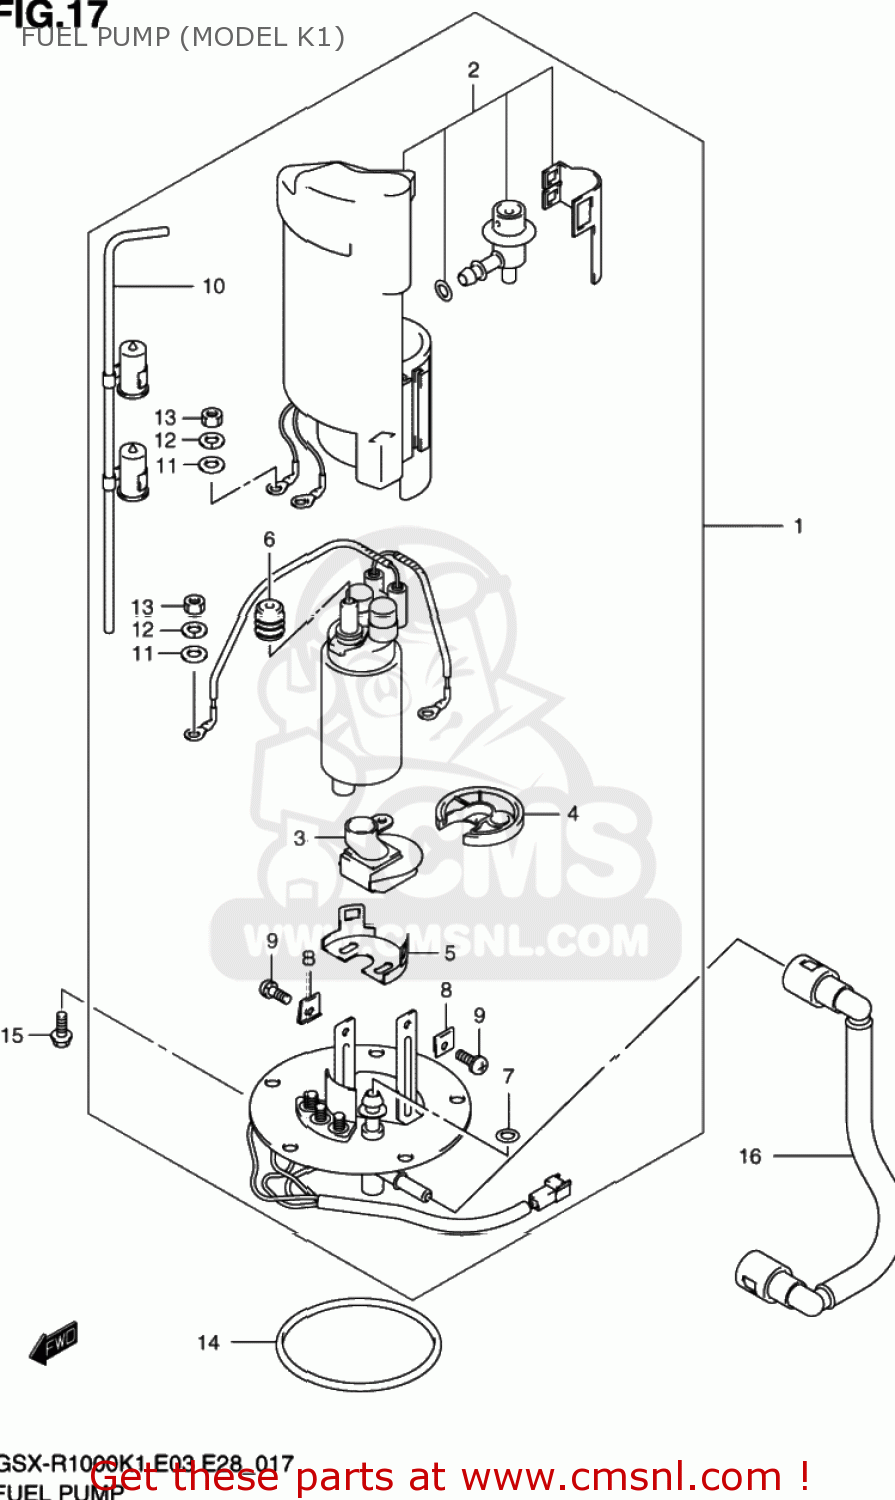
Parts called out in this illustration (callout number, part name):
1	PUMP ASSY,FUEL
2	FILTER ASSEMBLY,FUEL
3	STRAINER,FUEL PUMP
4	CUSHION
5	HOLDER,FUEL PUMP
6	BUSH,FUEL PUMP
7	O RING
8	NUT
9	SCREW
10	THERMISTOR COMP
11	WASHER
12	WASHER,SPRING
13	NUT
14	O RING,FUEL PUMP
15	BOLT
16	HOSE,FUEL
